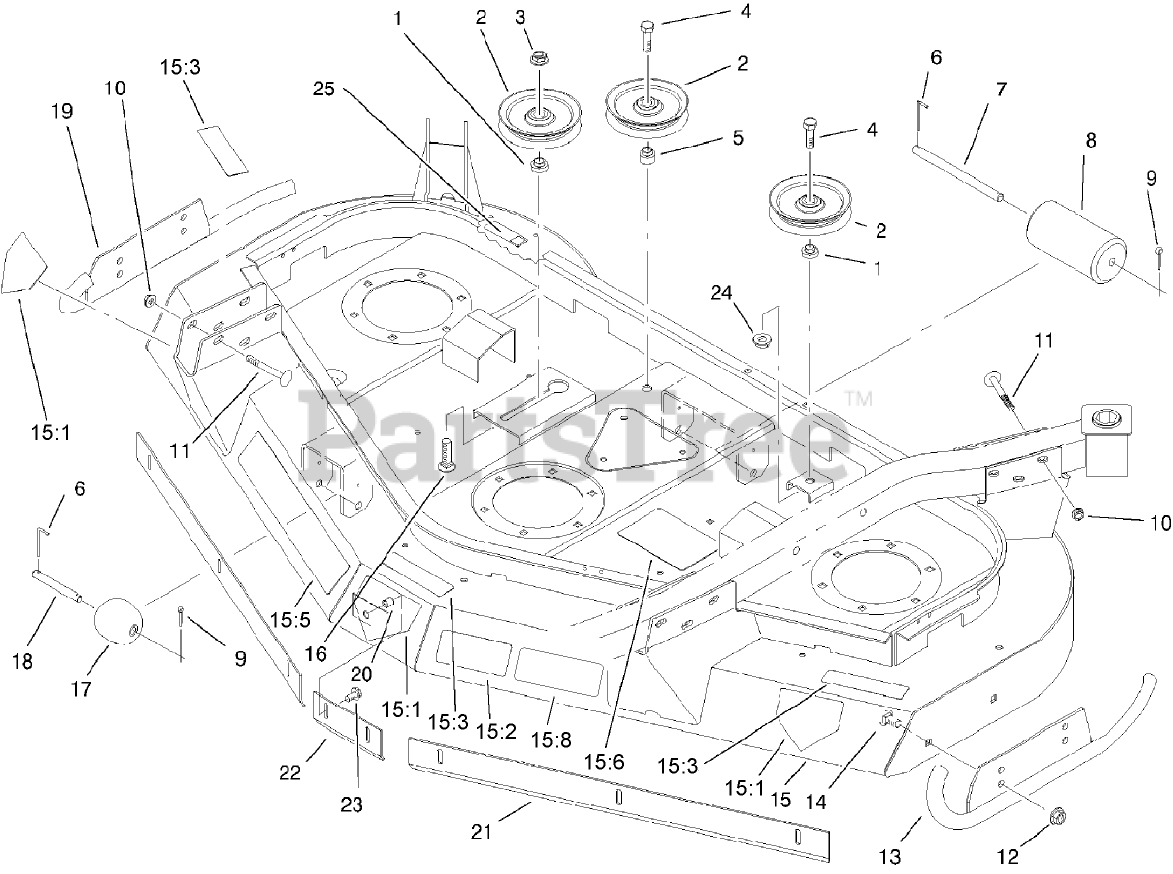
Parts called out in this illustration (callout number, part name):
1	SPACER-IDLER
2	PULLEY-IDLER
3	NUT-LOCK, NI
4	SCREW-HH
5	SPACER-IDLER, FLAT
6	PIN-SPECIAL
7	SHAFT-ROLLER
8	ROLLER-DECK
9	PIN-COTTER
10	NUT-HF
11	SCREW-CARR
12	NUT-HF
13	LH SKID ASM
14	SCREW-CARR
15	DECK ASM
15:1	DECAL-DANGER, CE
15:2	DECAL-TORQUE, BLADE BOLT
15:3	DECAL-DANGER
15:5	DECAL-GUARDIAN 62
15:6	DECAL-ROUTING, BELT
15:8	Decal-Warning
16	SCREW-CARR
17	ROLLER
18	SHAFT-ROLLER
19	RH SKID ASM
20	NUT-INSERT
21	BAFFLE-SIDE
22	BAFFLE-CENTER
23	SCREW-HHF
24	NUT-HF
25	Decal-Ansi
